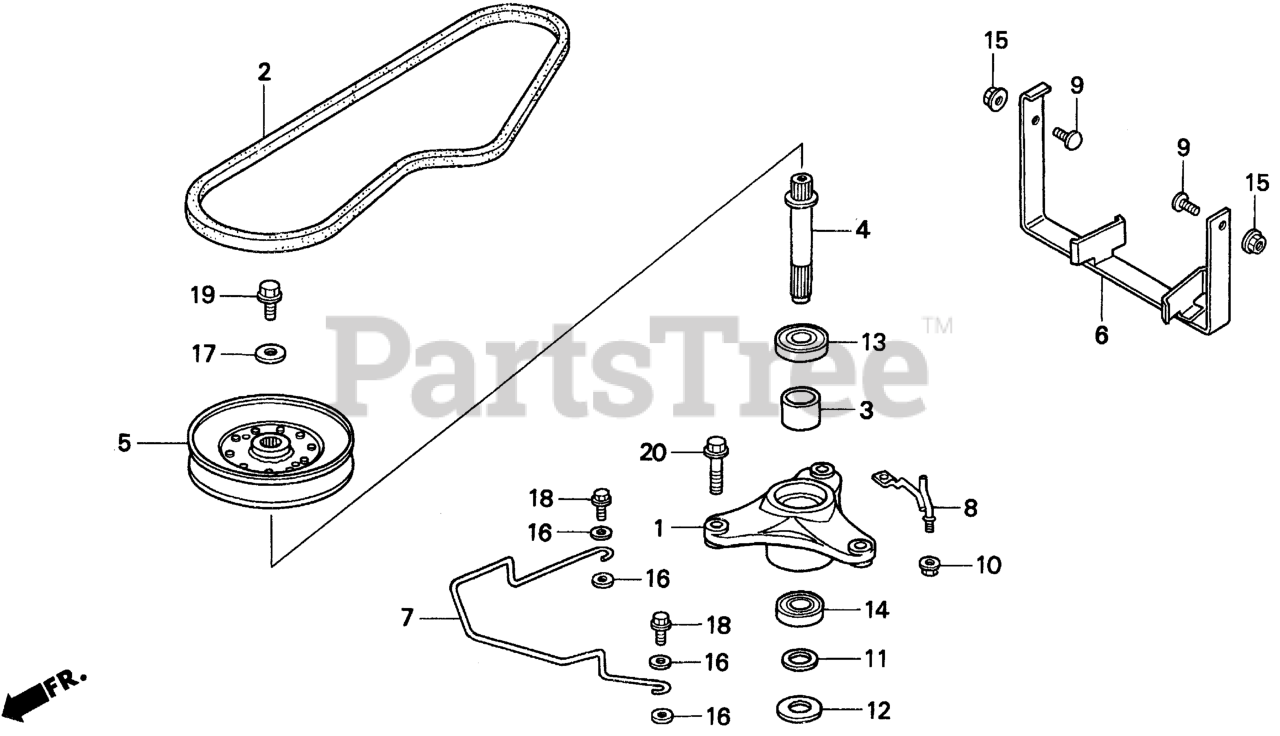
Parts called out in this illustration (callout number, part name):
1	HOUSING, BEARING
2	V-BELT, BLADE
3	COLLAR, BLADE SHAFT
4	SHAFT, BLADE
5	PULLEY, CUTTER
6	STOPPER A, BELT
7	STOPPER C, BELT
8	STOPPER E, BELT
9	BOLT, SPECIAL (9X15)
10	NUT, FLANGE (8MM)
11	WASHER, THRUST (20MM)
12	WASHER, BLADE HOLDER
13	BEARING, RADIAL BALL (6204)
14	BEARING, RADIAL BALL
15	NUT, FLANGE (8MM)
16	WASHER, PLAIN (8MM)
17	WASHER, PLAIN (10MM)
18	BOLT, FLANGE (6X25)
19	BOLT, FLANGE (10X16)
20	BOLT, FLANGE (10X35)
